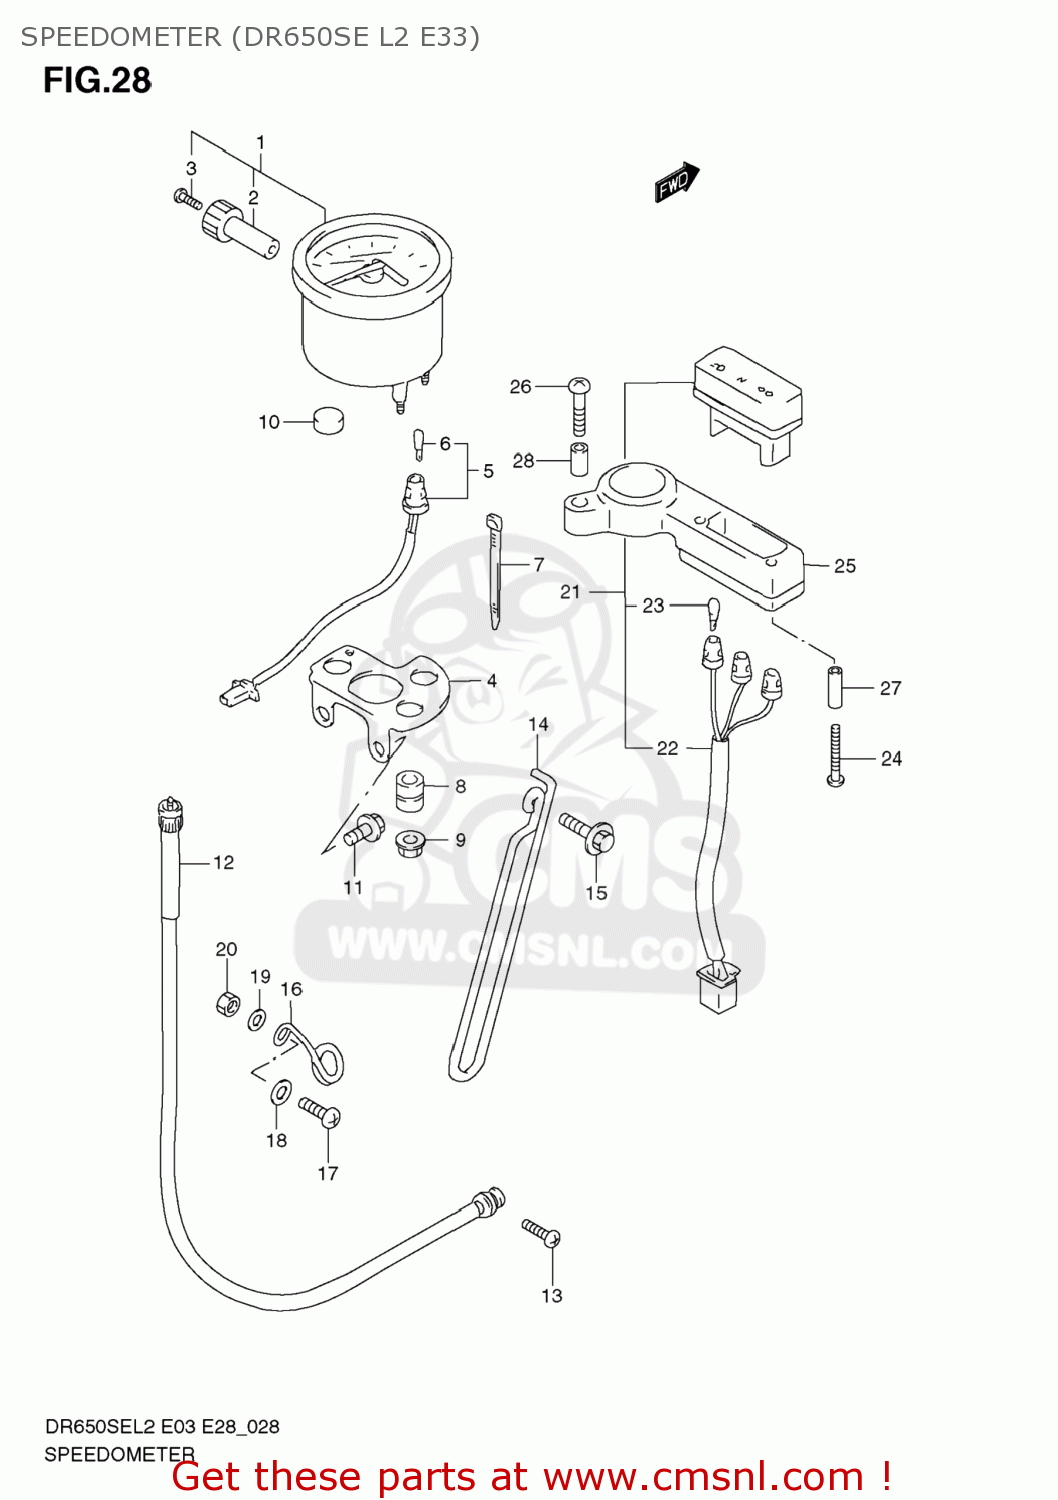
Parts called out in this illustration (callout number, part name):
1	SPEEDOMETER
2	KNOB,TRIP
3	SCREW,TRIP KNOB
4	BRACKET,METER
5	SOCKET
6	BULB(12V1.7W,T6.5)
7	CLAMP
8	CUSHION
9	NUT
10	CUSHION
11	BOLT
12	CABLE ASSY,SPEEDOMETER
13	SCREW
14	GUIDE,METER CABLE NO.2
15	BOLT(6X20)
16	GUIDE,SPEEDOMETER CABLE
17	SCREW
18	WASHER(6.5X18X1.6)
19	WASHER
20	NUT
21	BOX ASSY,PILOT LAMP
22	SOCKET & CORD
23	BULB(13.5V,2W,A7427)
24	SCREW
25	HOLDER,PILOT BOX
26	SCREW(6X25)
27	SPACER(4.5X6.5X25)
28	SPACER(6.1X8X15.5)
